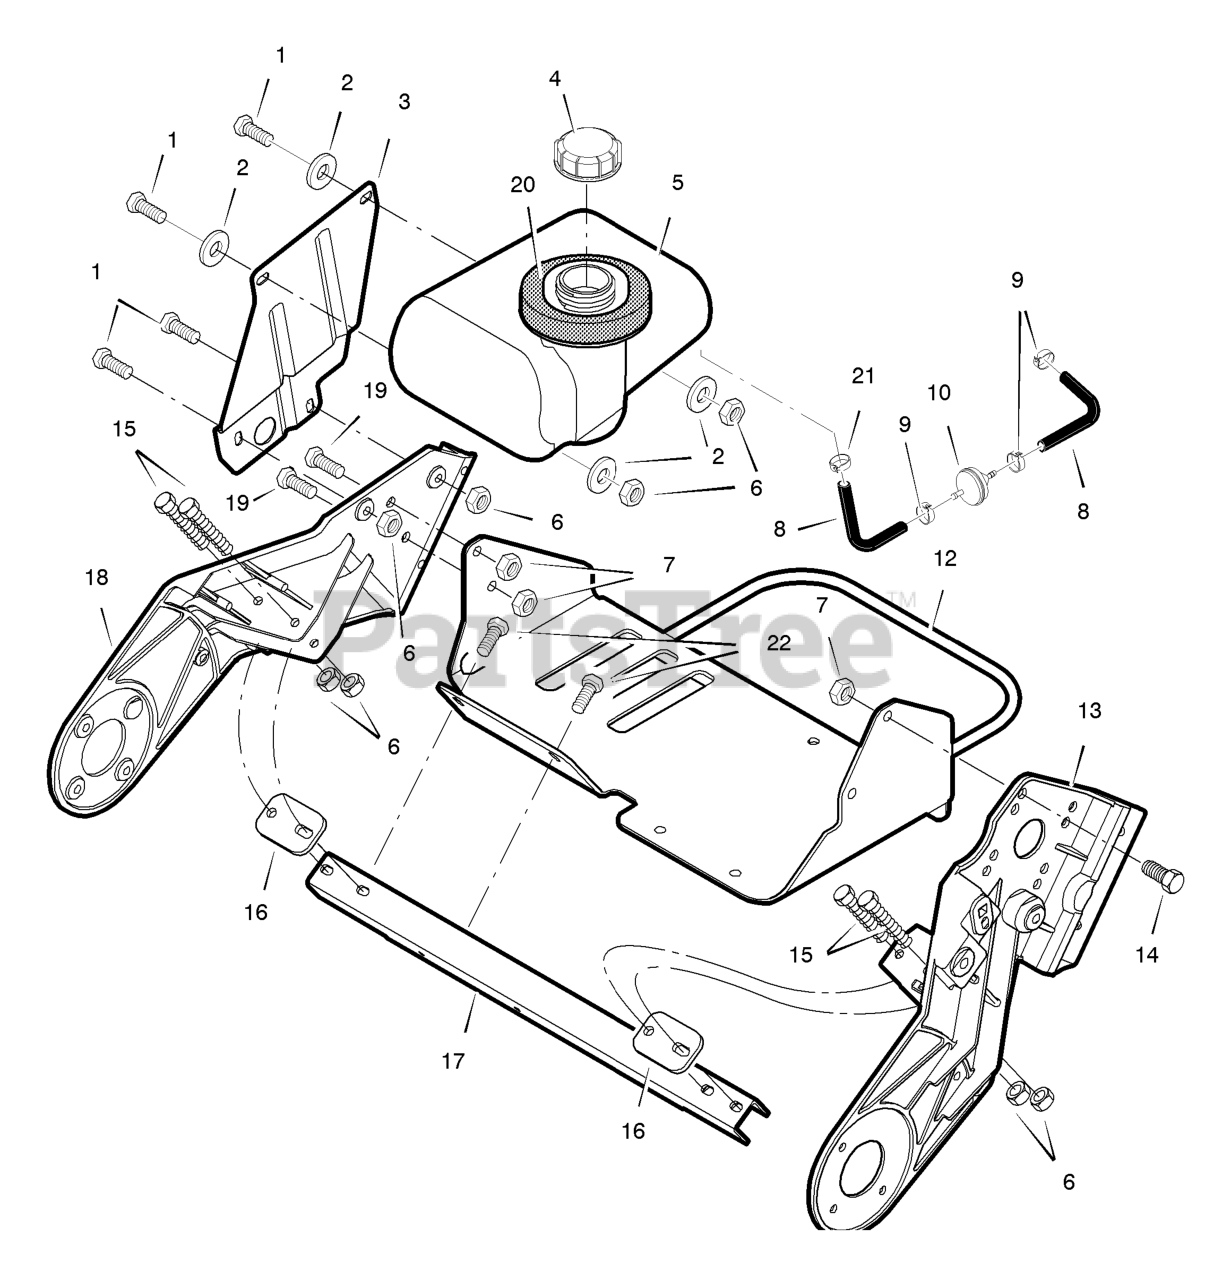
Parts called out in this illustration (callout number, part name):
1	Screw 1/4-20 x .75
2	Washer
3	Bracket, Fuel Tank
4	Cap, Fuel Tank
5	Tank, Fuel
6	Nut, Hex 1/4-20
7	Nut, Hex 5/16-18
8	HOSE, FUEL 12 INCHES
9	Clamp, Fuel Line
10	Filter, Fuel Line
12	Cradle Assembly, Engine
14	Screw, 5/16-18 x .63
15	Screw, 1/4-20 x 2.00
16	Plate, Mounting Support
17	Support, Frame
18	Frame, RH
19	Screw, 5/16-18 x 0.75
20	Ring, Foam
21	Clamp, Fuel Line -Screw Type
22	Screw, 1/4-20 x .625
